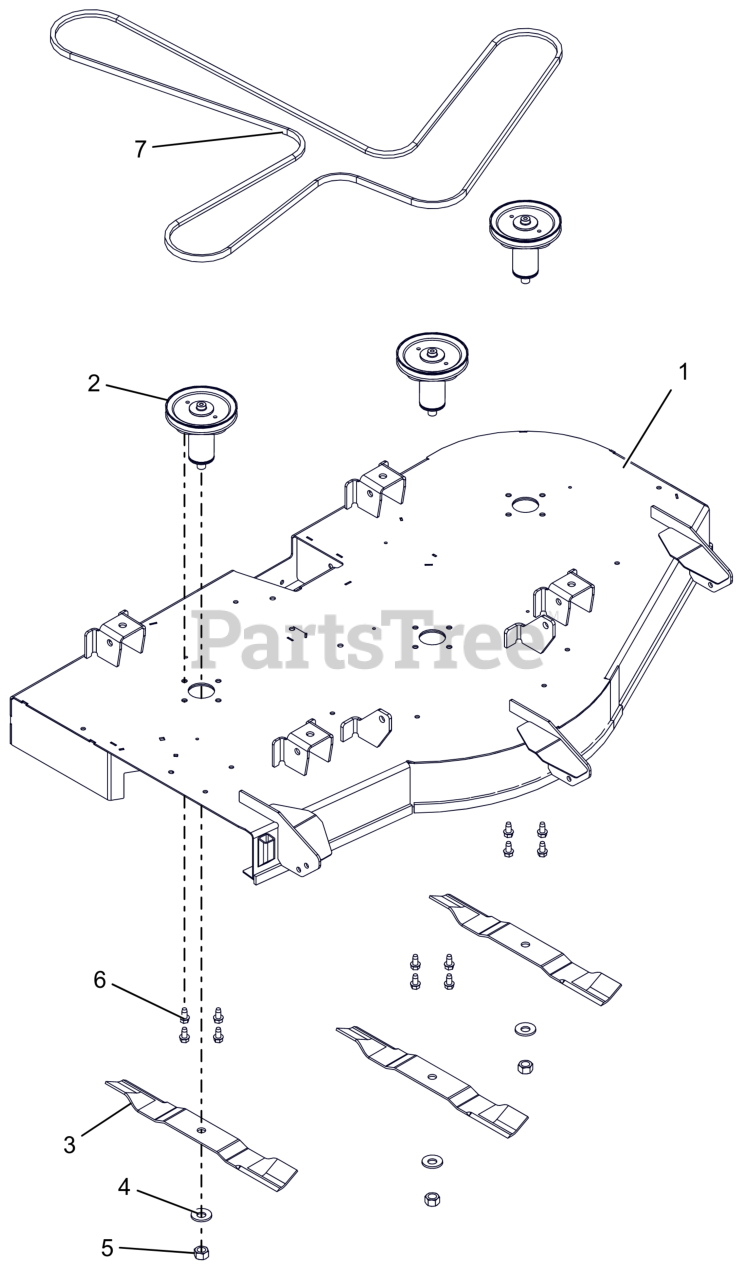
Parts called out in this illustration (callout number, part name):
1	KIT, 52" ARIENS DECK W/DECALS
2	KIT, DECK SPINDLE ASM-52
3	BLADE, 18" - 30 DEG .5 OFFSET
4	WSHR-BLVL .669X1.535X.138
5	NUT-STD .625-18 ZCC
6	SCR,TAP .375-16X.75 HWH TR ZCC
7	V-BELT, HA-WRAPPED
